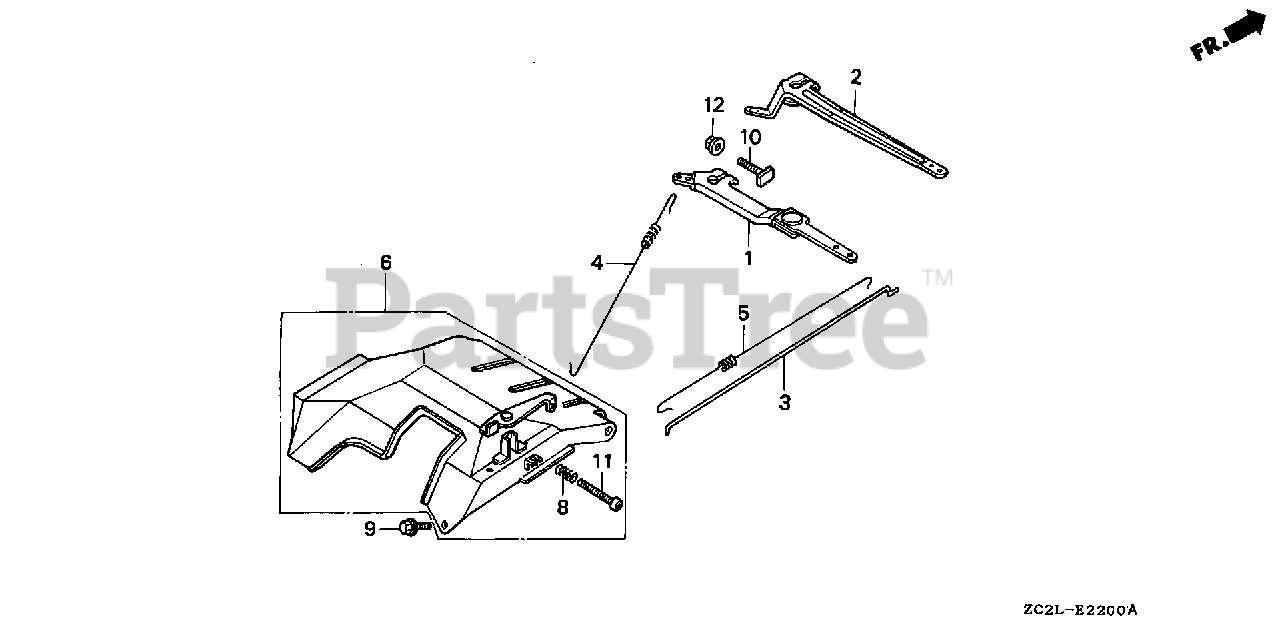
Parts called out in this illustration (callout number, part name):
2	ARM, GOVERNOR
3	ROD, GOVERNOR
4	SPRING, GOVERNOR (L=132.0MM)
5	SPRING, THROTTLE RETURN
6	CONTROL ASSY.
8	SPRING, CONTROL ADJUSTING
9	BOLT, FLANGE (6X12) (CT200)
10	BOLT, GOVERNOR ARM
11	SCREW, PAN (5X45)
12	NUT, FLANGE (6MM)
